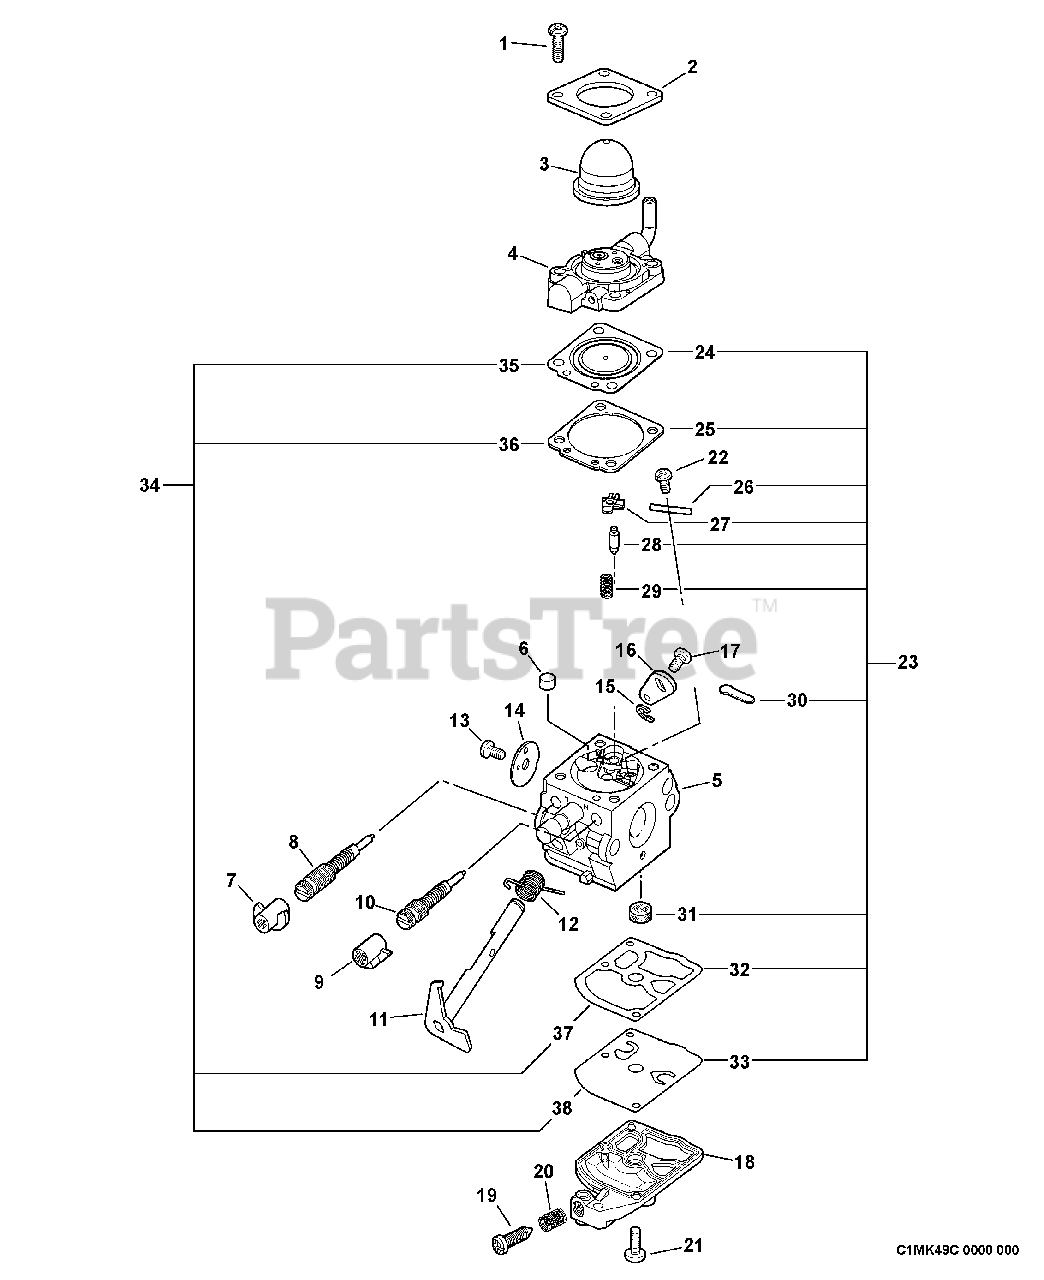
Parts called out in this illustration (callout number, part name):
1	SCREW, RETAINER
2	RETAINER, PURGE BULB
3	BULB, PURGE
4	BASE, PURGE
5	BODY, CARBURETOR
6	NOZZLE, CHECK VALVE
7	CAP, LIMITER
8	NEEDLE - LOW SPEED
9	CAP, LIMITER
10	NEEDLE - HIGH SPEED
11	SHAFT, THROTTLE
12	SPRING, TRIGGER
14	VALVE, THROTTLE
15	RING, RETAINING
16	LEVER, THROTTLE
18	COVER, FUEL PUMP
19	SCREW, IDLE ADJUST
20	SPRING, IDLE ADJUST
21	SCREW, PUMP COVER
22	SCREW, METERING LEVER PIN
23	REPAIR KIT
24	DIAPHRAGM, METERING
25	GASKET, DIAPHRAGM
26	PIN, METERING LEVER
27	LEVER, METERING
28	SPRING, METERING LEVER
29	VALVE, INLET NEEDLE
30	PLUG, WELCH
31	STRAINER
32	GASKET, PUMP
33	DIAPHRAGM, PUMP
34	DIAPHRAGM/GASKET KIT
35	DIAPHRAGM, METERING
36	GASKET, DIAPHRAGM
37	DIAPHRAGM, PUMP
38	GASKET, PUMP
